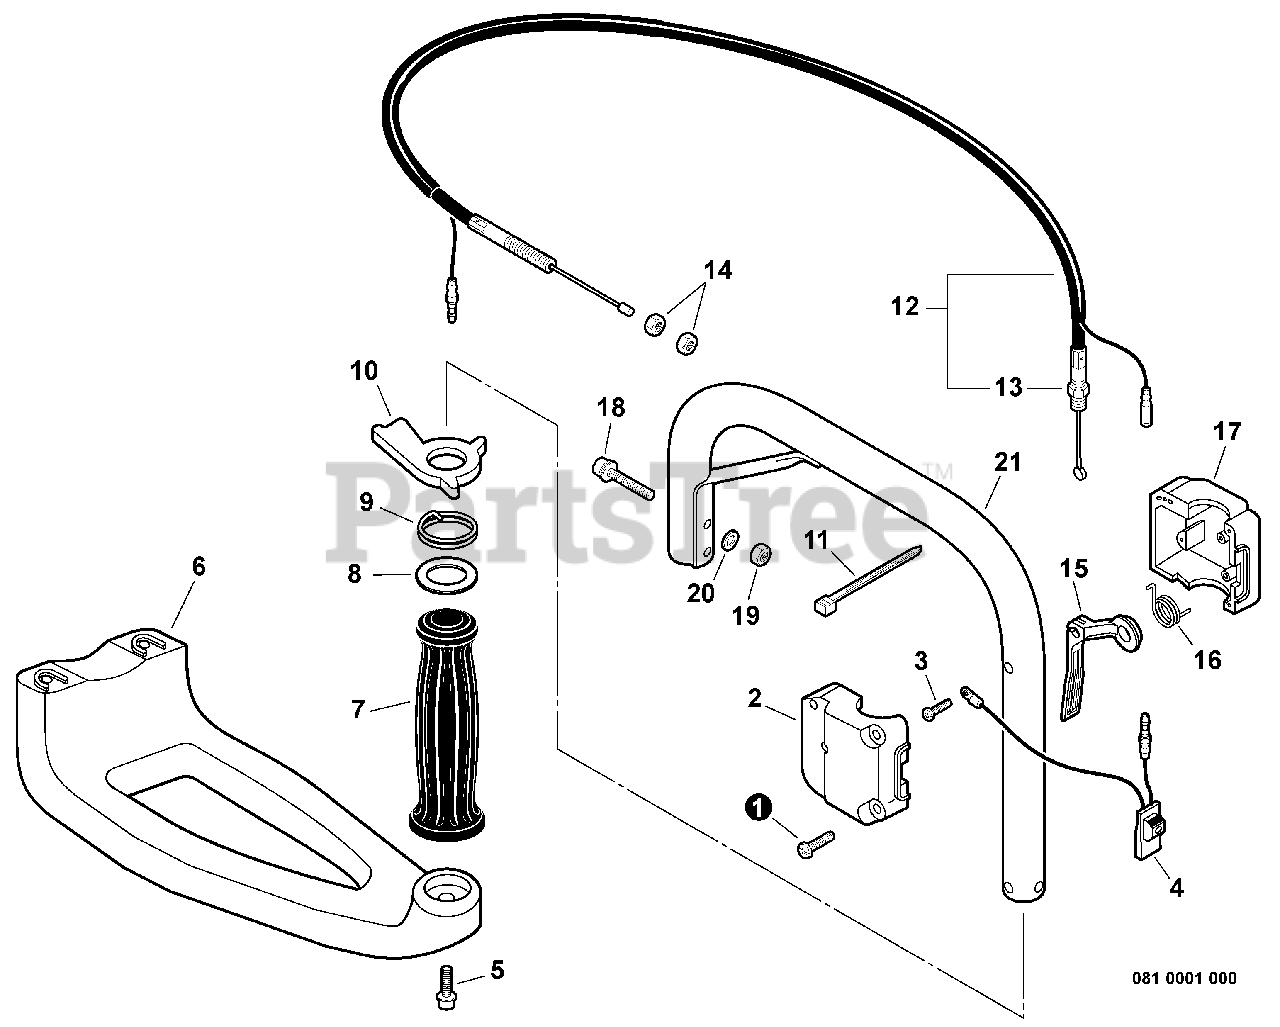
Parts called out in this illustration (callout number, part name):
1	SCREW - 4X25
2	BRACKET, THROTTLE CONTROL - LEFT
3	SCREW - 4X30
4	IGNITION SWITCH ASSY
5	SCREW - 5X16
7	GRIP, HANDLE - RIGHT
9	SPRING, LOCKOUT LEVER
10	LEVER, TRIGGER LOCKOUT
11	TIE, CABLE
12	CONTROL CABLE ASSY
15	TRIGGER, THROTTLE
16	SPRING, TRIGGER
17	BRACKET, THROTTLE CONTROL - RIGHT
18	SCREW - 5X35
19	LOCKNUT - 5
20	WASHER - 5
21	HANDLE - REAR
